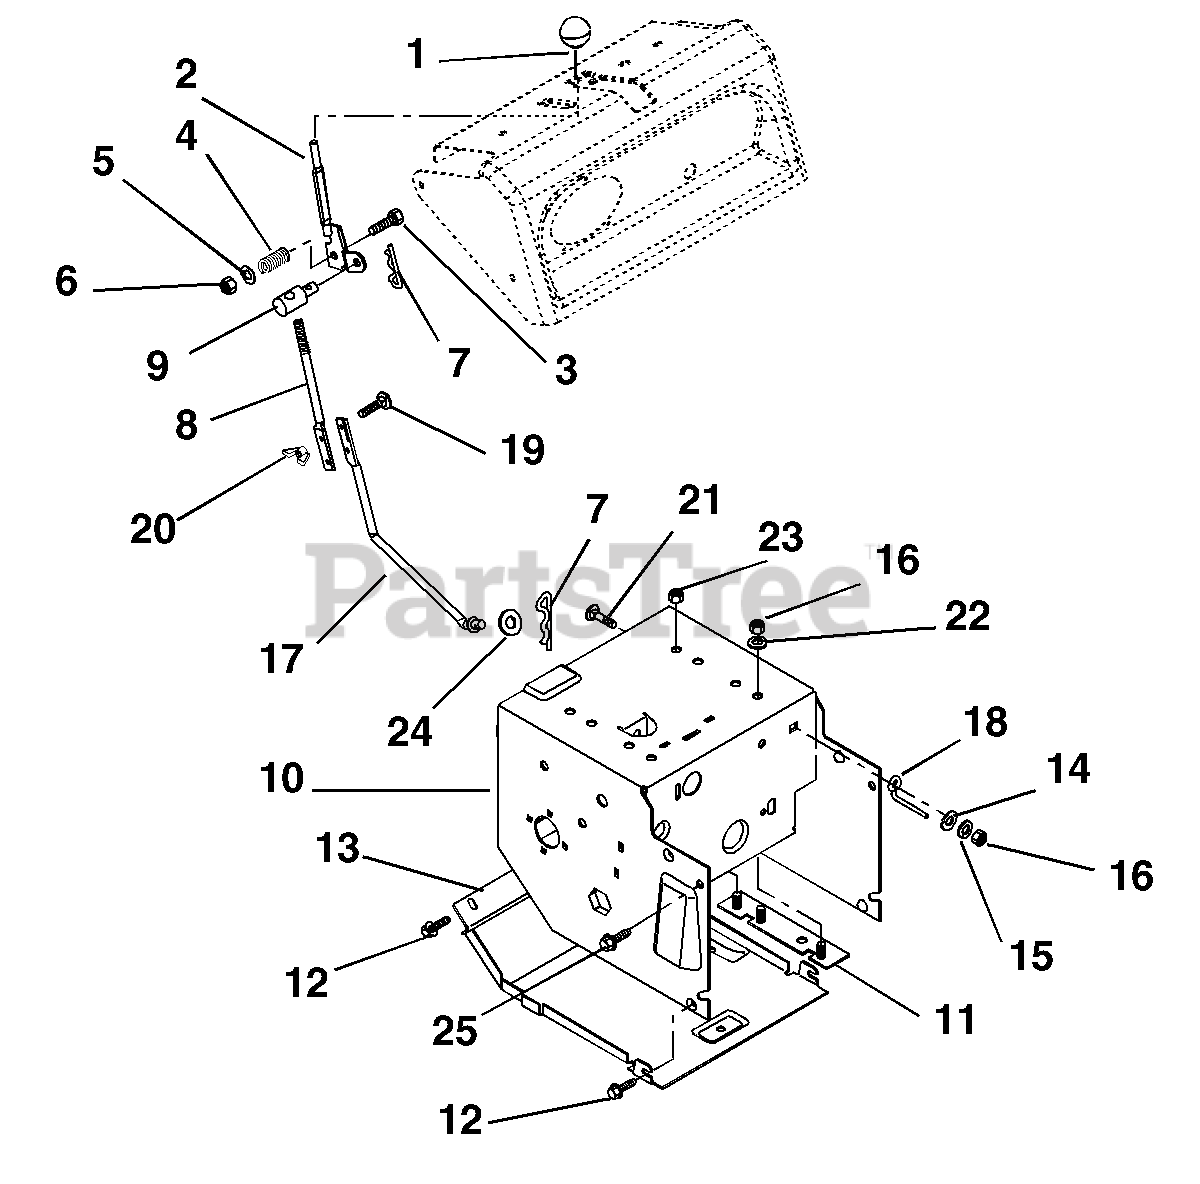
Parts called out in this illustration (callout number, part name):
1	KNOB,BALL -BLACK 1.47" .375-16
2	LEVER, SHIFT
3	@BLT-HEX .38-16X2.25 GR5 YWZC
4	SG-COMP .125X.781X1.250
5	@WSHR-FL-STL.438X1.00X.083 YWZ
6	@NUT-LK-CTR .38-16 YWZC
7	PIN-HAIR INT .08X.18X1.18 YWZC
8	ROD, SHIFT-UPPER
9	PIVOT, ROD (TRUNNION ) .50
11	ENGINE MOUNT, 5L,7L,8R
12	@SCR-TAP .25-20X.37 HWH YWZ TR
13	COVER BOTTOM
14	@WSHR-FL-STL.38X.875X.083 YWZC
15	@WSHR-LK .31X.078 REG YWZC
16	@NUT-HEX .31-18 YWZC
17	ROD, SHIFT-LOWER
18	BELT FINGER LOWER
19	@BLT-RDHDSQNK .25-20X1.00 G5YZ
20	NUT-LK WING .250-20 YWZC
21	@BLT-RDHDSQNK .31-18X1.00 G5YZ
22	WSHR-LK .312X.097 HVY YWZC
23	@NUT-LK-NYL .312-18 YWZC
24	@WSHR-FL-STL.531X1.06X.095YWZC
25	@SCR-TAP .38-16X.50 HWH TR YWZ
